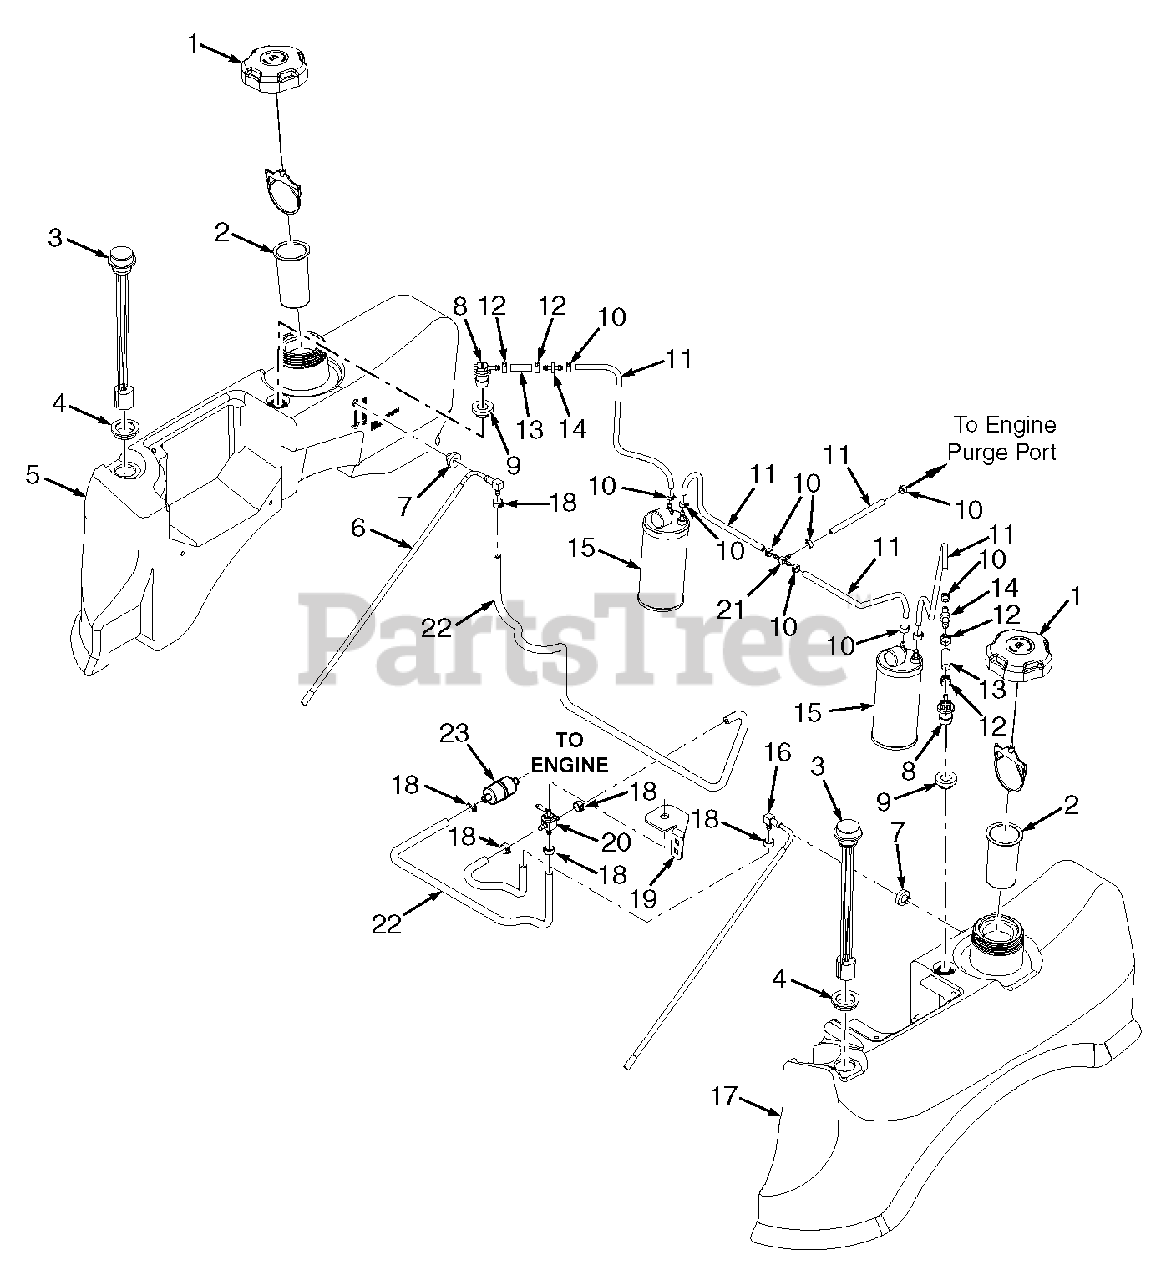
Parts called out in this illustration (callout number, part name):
1	Fuel Cap, Tethered
1	Fuel Cap, Tethered (California Only)
2	Tube, Fuel Tank Insert - 4"
3	Fuel Gauge Assembly
4	Seal, Fuel Gauge
5	Fuel Tank Assembly, RH
6	Fuel Tube Assembly
7	Bushing, .56 Viton
8	Remote Vent
9	Grommet, Viton
10	Clamp, Vapor Recovery Hose
11	Hose, 3/16" (order by inch)
12	Clamp, Fuel Hose 7/32
13	Hose, Vapor Recovery (order by inch)
14	Mender, 1/4 x 3/16
15	Carbon Canister, 400cc
15	Dust Filter, Carbon Canister
16	Fuel Tube Assembly, LH
17	Fuel Tank Assembly, LH
18	Clamp, Fuel Hose 1/4" I.D.
19	Mounting Bracket, Fuel Valve
20	Valve, Fuel Shut Off
21	Tee, 3/16 x 3/16 x 3/16 Union, Hose Barb
22	Hose, Non-Perm Fuel 1/4" I.D.
23	Fuel Filter
